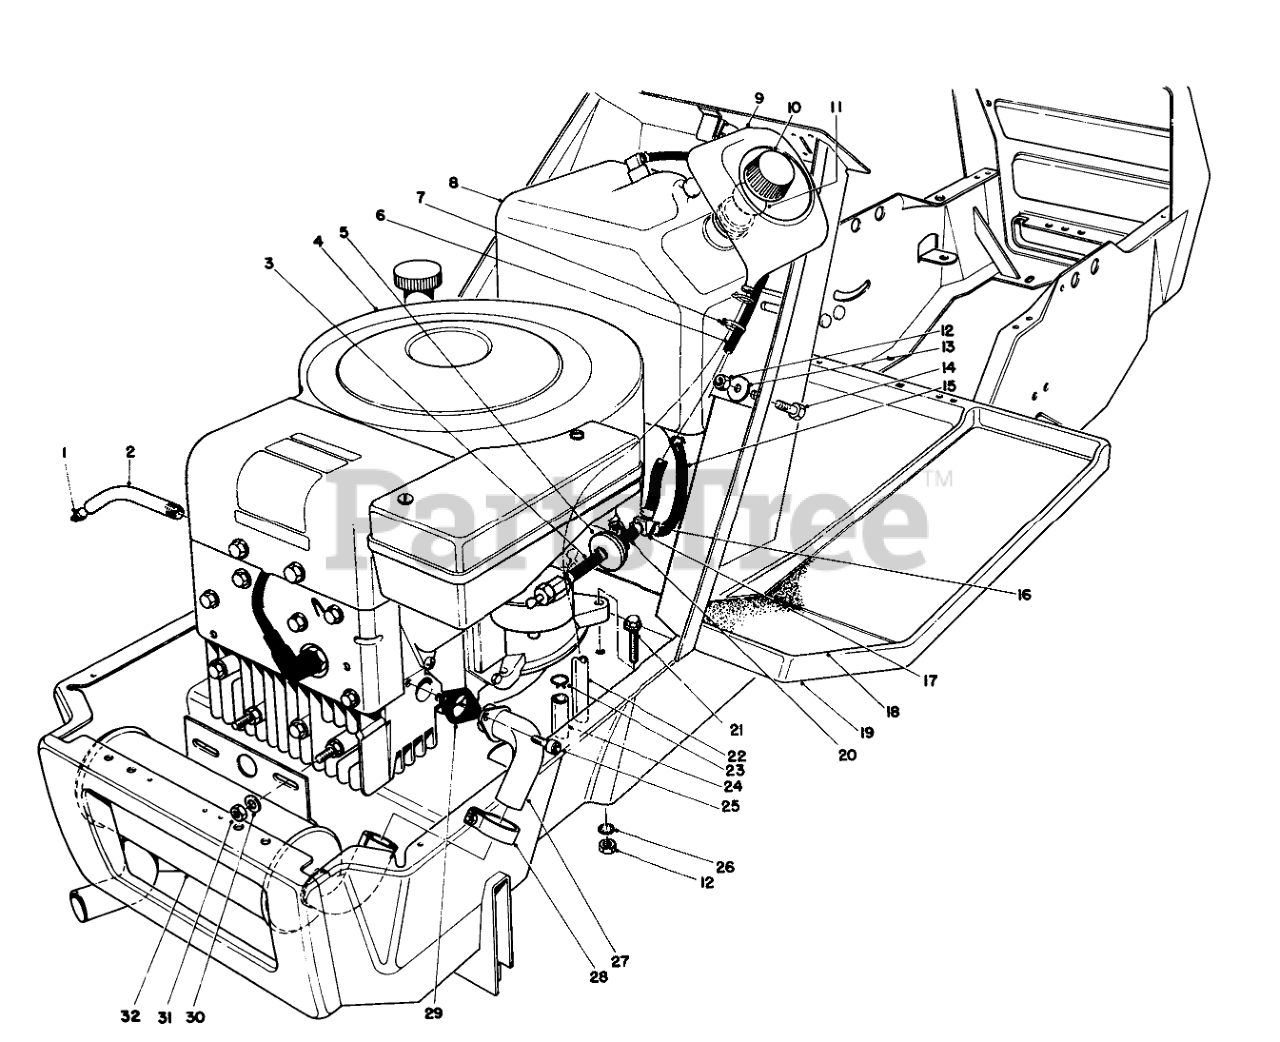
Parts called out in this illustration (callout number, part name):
1	PLUG-PIPE, SQH
2	OIL DRAIN TUBE
3	Hose-Gas
4	Engine
5	Fuel Filter
6	HOSE -RETURN
7	TIE-CABLE
8	Gas Tank Assy. (Incl. Ref. #9)
9	Funnel-Overflow
10	Gas Cap Assy. (Incl. Ref. #11)
11	GAS CAP GASKET
12	NUT-LOCK, NI
13	WASHER
14	Screw
15	HOSE-FUEL
16	FUEL HOSE CLAMP
17	Fitting-Barbed Y
18	LH FOOT TREAD
19	Frame
20	GAS HOSE
21	SCREW-HH
22	FUNNEL HOSE
23	HOSE CLAMP
24	CARB DRAIN HOSE
25	SCREW-HSH
26	WASHER-LOCK, INTERNAL
27	10 HP EXHAUST PIPE WA
28	MUFFLER CLAMP
29	Exhaust Gasket
30	WASHER-PLAIN
31	NUT-LOCK, CONE
32	EXHAUST MUFFLER 10 HP
